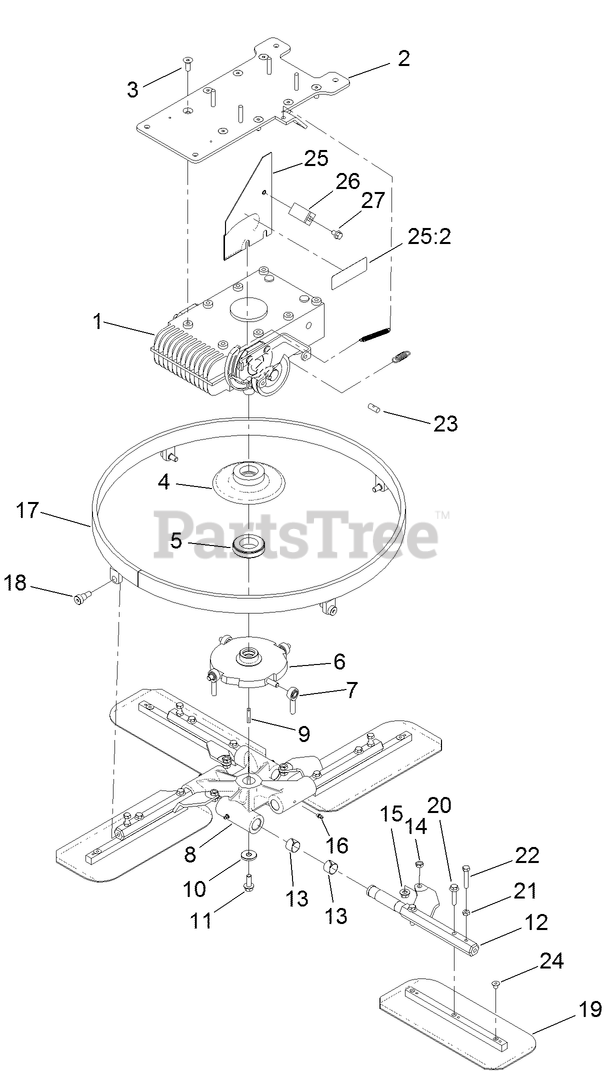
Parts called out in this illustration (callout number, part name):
1	GEARBOX ASM
2	ENGINE BASE ASSEMBLY PT-36
3	SCREW
4	COVER-PLATE, THRUST
5	BEARING-BALL
6	PLATE-TILT
7	BEARING-END, ROD
8	SPIDER-4 ARM
10	WASHER-FLAT
11	SCREW-HHF
13	BUSHING-SLEEVE, NYLON
14	NUT-HJ
15	NUT-FLANGE, LOCK
16	FITTING-GREASE
17	ROTATING-RING
18	SCREW-HSBH
19	BLADE-COMBINATION
20	SCREW-HHF
21	NUT-JAM
22	SCREW-HH
23	ROD-PIVOT, CABLE
24	CARPLUG-RED
25	REAR BELT GUARD ASM
25:2	DECAL-WARNING
26	GUIDE-BELT
27	SCREW-FLANGE
